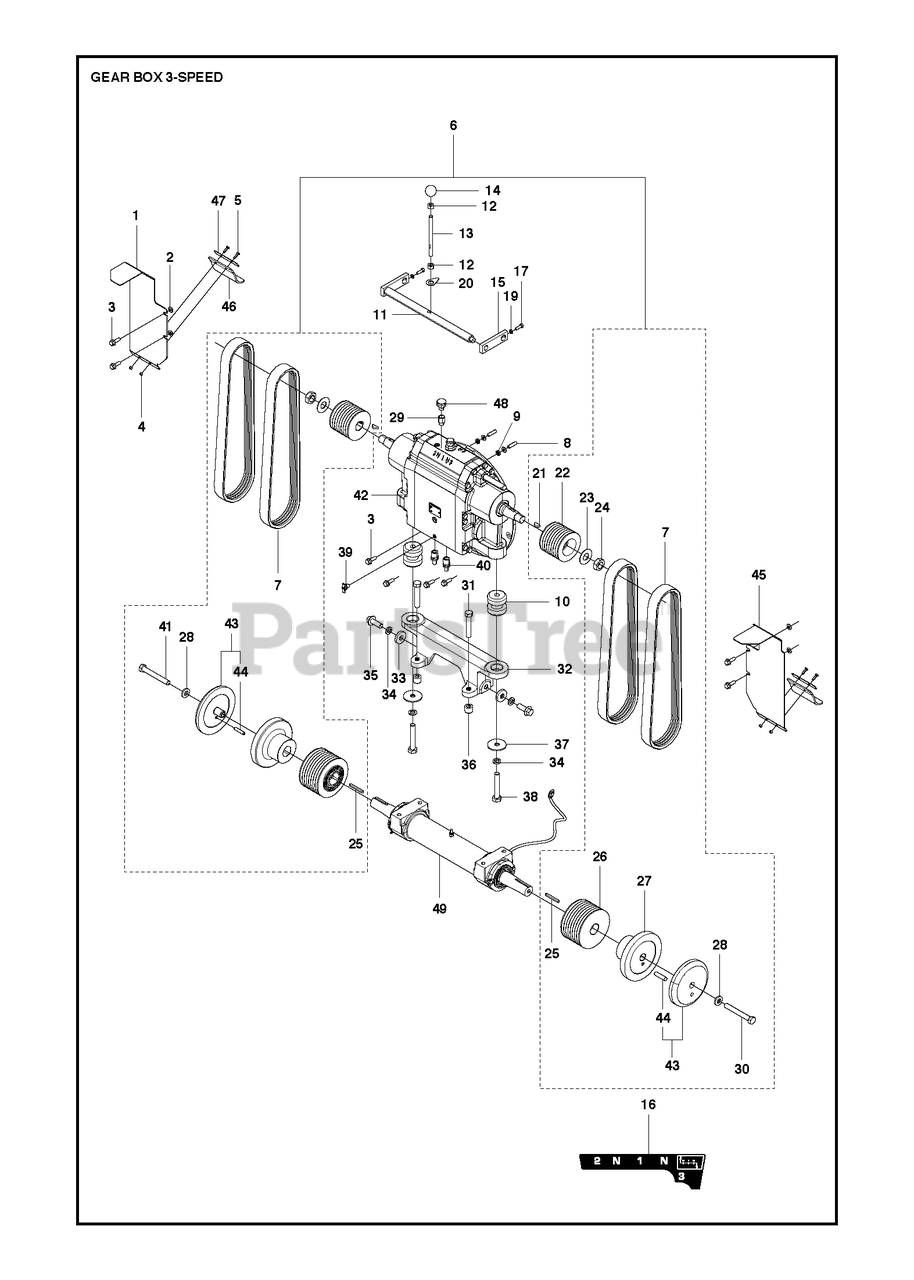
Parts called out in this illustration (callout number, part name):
2	WASHER
4	HEXAGON LOCKING NUT
10	ANTIVIBRATION ELEMENT
18	SCREW EHHM
22	PULLEY"30"", 36"", 42"""
30	SCREW"26"", 30"", 36"""
41	SCREW"26"", 30"", 36"""
42	GEARBOXAfter S/N #001334666001
42	KITBefore S/N #001334666001
45	BELT GUARD"36"", 42"""
46	SPLASH GUARDLeft Side
